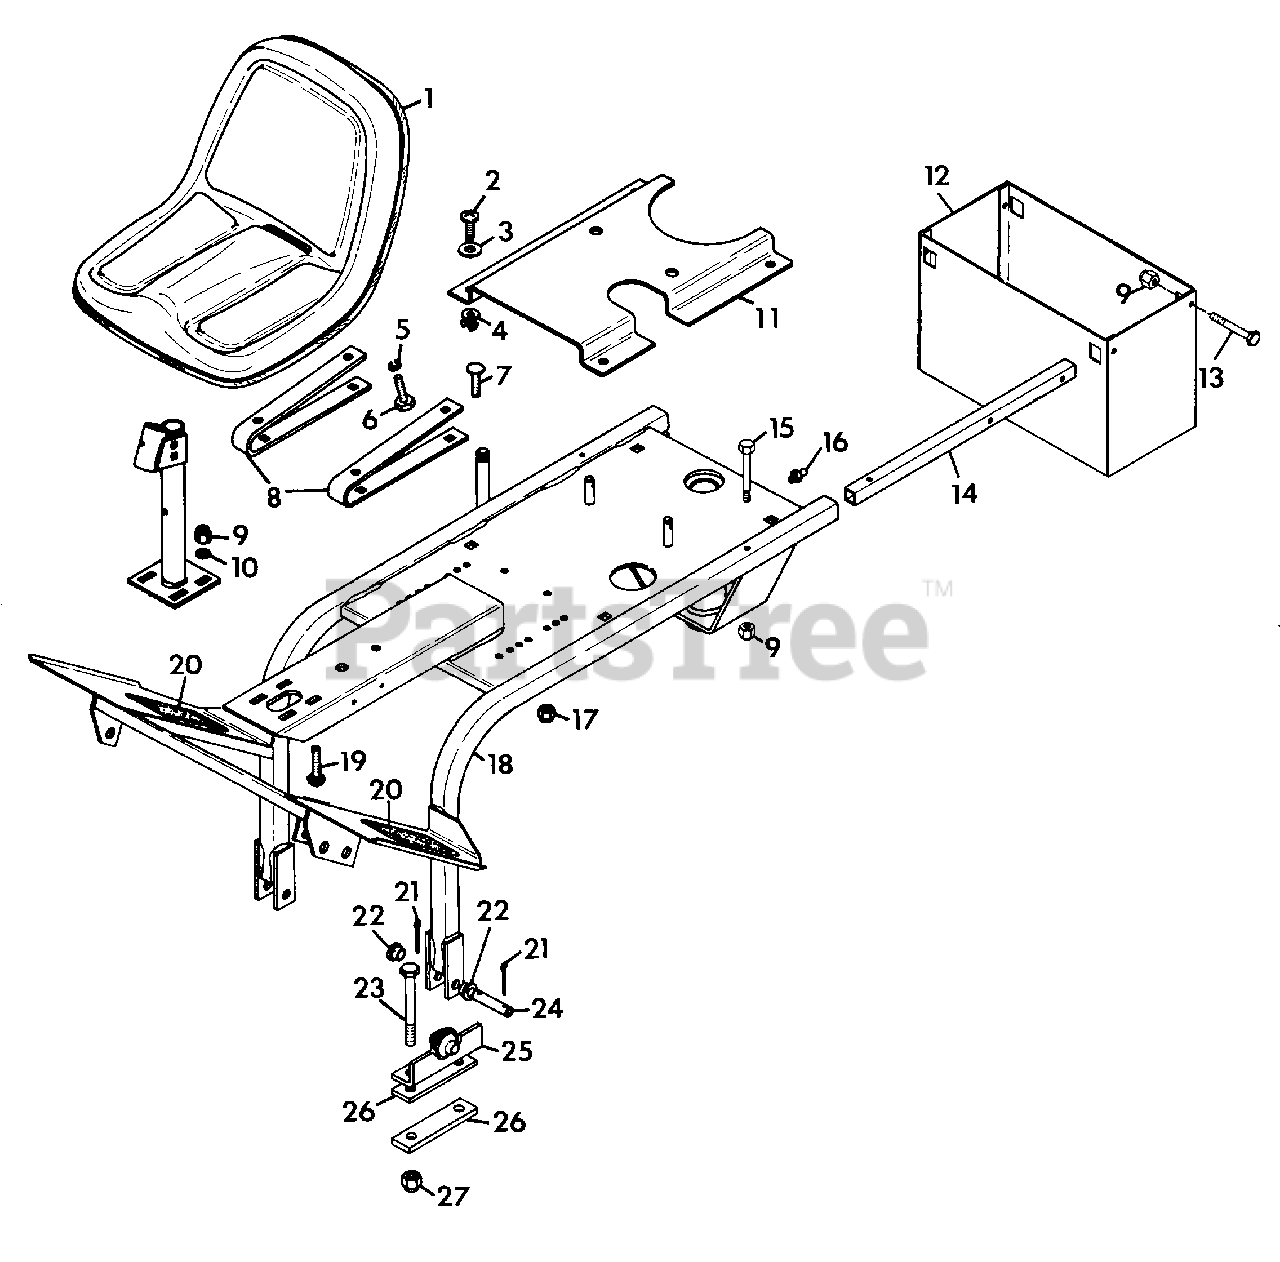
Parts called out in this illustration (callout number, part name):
1	SEAT, HIGH BACK
2	SCREW, TAPPING 1/4-20X.625 PHD
3	WASHER, FLAT .344X.688X.065
4	GROMMET, PLASTIC
5	WASHER, LOCK 5/16 REG.
6	BOLT, HEX 5/16-18X.75
7	BOLT, CARRIAGE 5/16-18X1.00
8	SPRING, SEAT
9	NUT, LOCK 3/8-16
10	WASHER, FLAT .406X.812X.065
11	COVER, CHAIN
12	WELDMENT, WEIGHT BOX
13	BOLT, HEX 3/8-16X2.25
14	TUBE, SUPPORT
15	BOLT, HEX 3/8-16X2.75
16	FITTING, LUBE 1/4-28
17	NUT, LOCK 5/16-18
18	FRAME, O.F.C.
19	BOLT, 3/8-16X1.00 RD HD SQ NK
20	COVER, LARGE FOOTBOARD
21	PIN, COTTER .125X1.500
22	BUSHING
23	BOLT, HEX 1/2-13X5.50
24	PIN, .750X3.3
25	WELDMENT, BRACKET MOUNTING
26	PLATE, AXLE
27	NUT, LOCK 1/2-13
NS	DECAL, GRAVELY LOGO
NS	DECAL, PRO MASTER-50
NS	DECAL, AMERICA
